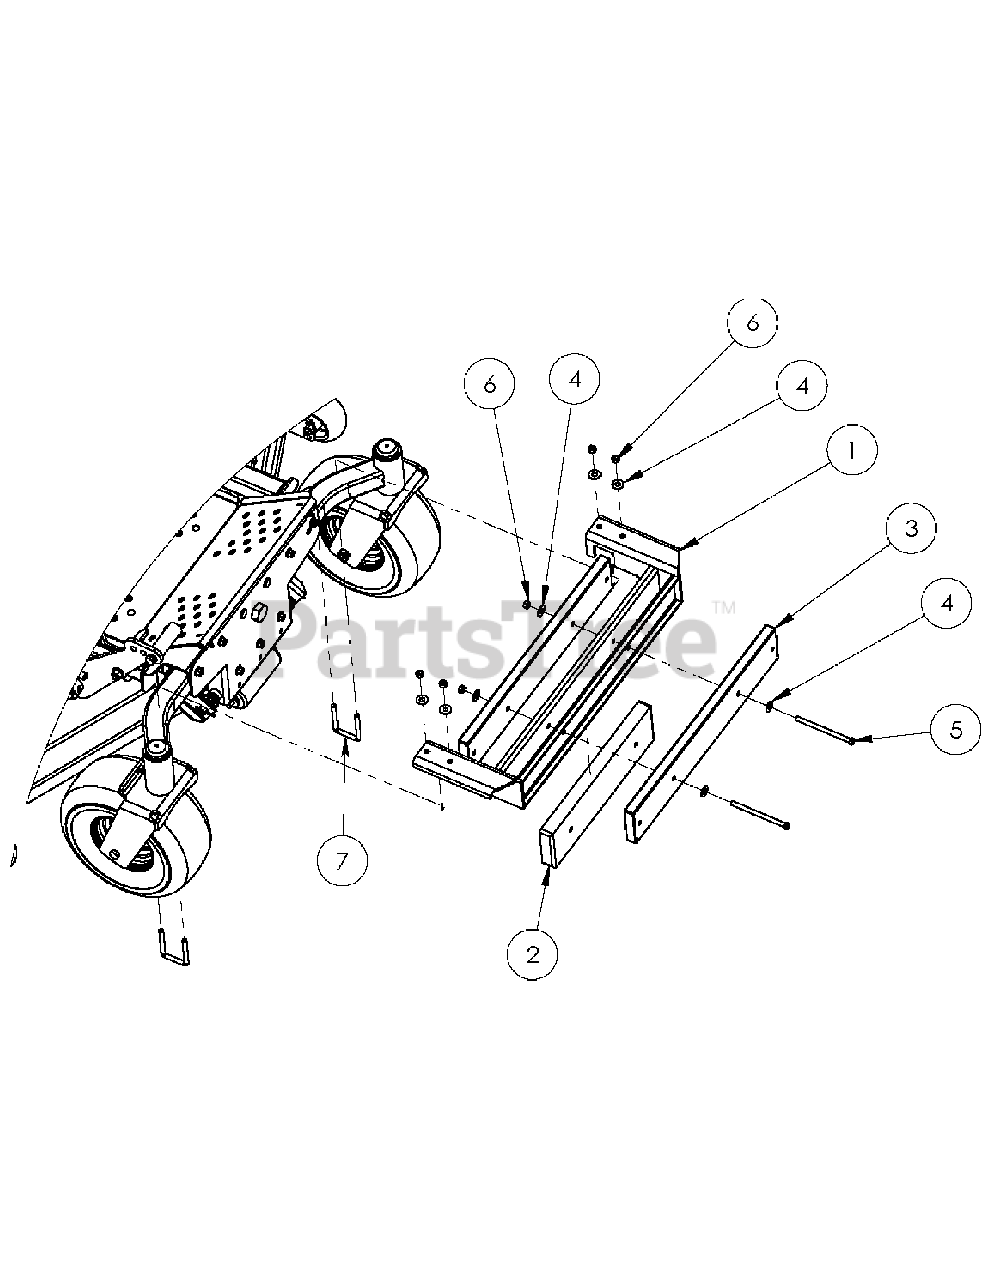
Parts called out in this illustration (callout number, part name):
1	WEIGHT BRACKET
2	BAR WEIGHT
4	3/8" FLAT WASHER
5	CAP SCREW 3/8-16 X 5 1/2" LONG
6	HEX NUT, NYLON INSERT-3/8"-16
